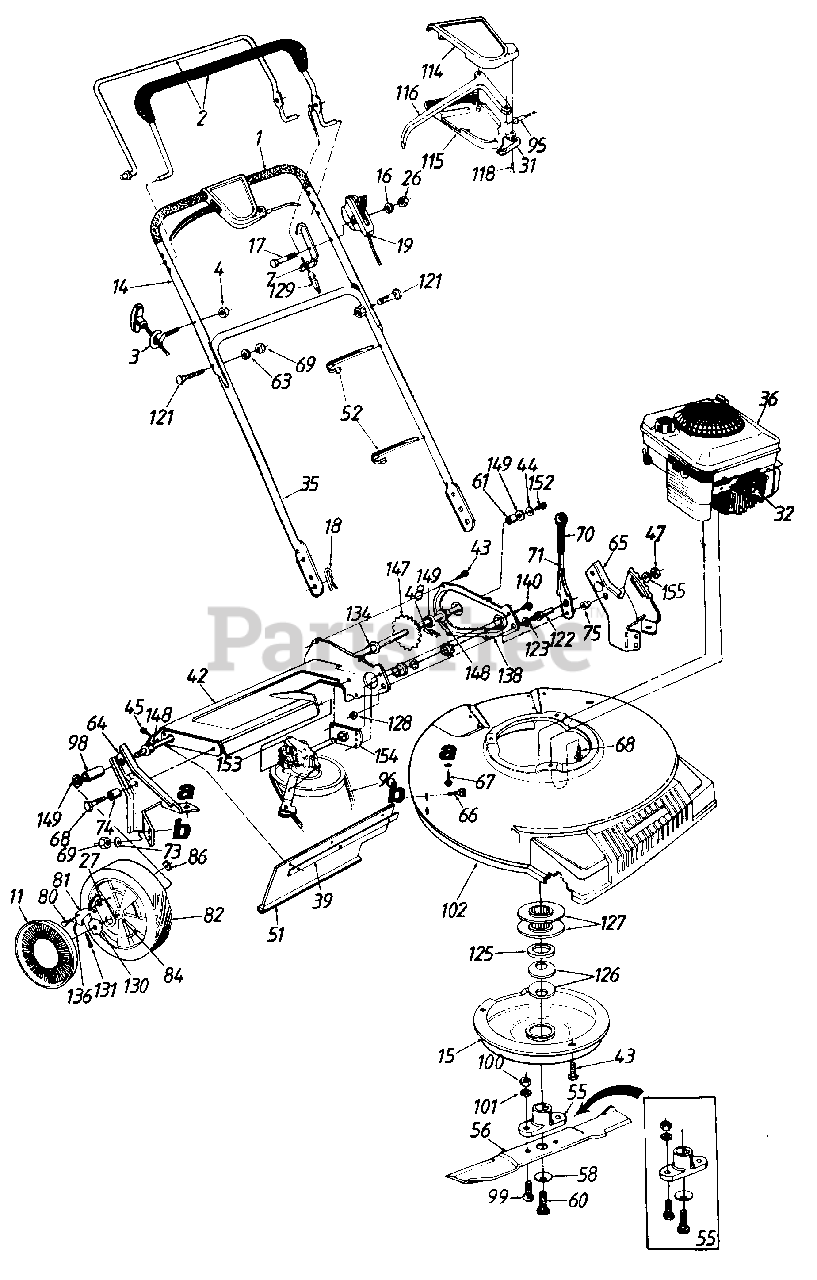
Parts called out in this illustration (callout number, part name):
1	Grip
2	Control Handle Ass'y.
3	Rope Guide Bolt
4	Hex L-Nut 1/4-20 Thd.
7	Cable Brkt.
11	Hub Cap
14	Upper Handle
17	Hex Bolt 1/4-20 x 1.875" Lg.
18	Internal Cotter Pin 5/16" Dia.
19	Throttle Control Ass'y.
26	Hex Nut 1/4-20 Thd.
27	Pawl Plate
31	S.P. Control Cover
32	Spark Plug Insulator
35	Lower Handle
36	Engine
39	Retaining Strip
42	Chain-Axle Ass'y.
43	Hex B-Tap Scr. 1/4" x .38"
44	Bell-Wash. 1/4" I.D.
45	Hex AB-Tap Scr. 1/4 x .62"
47	Hex Patch L-Nut 3/8-24 Thd.
48	#48 Chain .500" Pitch x 38 Links
51	Rear Flap 3.75" x 17.30" Lg.
52	Cable Tie
55	Blade Adapter Kit
56	21" Mulching Blade
58	Bell-Wash. .47" I.D. x 1.14" O.D.
60	Hex Bolt 7/16-20 x 2.5"
61	Spacer. 513" I.D.
63	L-Wash. 5/16" I.D.
64	R.H. Handle Wheel Brkt. Ass'y.
65	L.H. Handle Wheel Brkt. Ass'y.
66	Carriage Bolt 5/16-18 x .62"
67	Hex B-Tap Scr. 5/16-18
68	Hex TT-Tap Scr. 3/8-16
69	Hex Nut 5/16-18 Thd.
71	Height Adj. Lever
73	Bell-Wash. 5/16" I.D.
74	Spacer.383" I.D.
75	Shld. Spacer .5" Dia.
80	Shld. Scr. .342" Dia. x .268
81	Pawl
82	Wheel Ass'y. Comp.-Rear
84	Sleeve Bearing 1/2" I.D.
86	Flat Nut 1/4-20 Thd.
95	S.P. Cable-44" Lg.
96	"V"-Belt
98	Sleeve.526" I.D.
99	Hex Bolt 3/8-24 x 1.0" Lg.
100	Hex Nut 3/8-24 Thd.
101	L-Wash. 3/8" I.D.
115	Self-Propelled Control Cover
116	Control Lever
118	Fl-"C"-Sunk Hd. Tap Scr. #10 x 75n Lg.
121	Curved Carr. Bolt 5/16-18 x 1.38" Lg.
122	Shld. Pin 1.43" Lg.
123	L-Wash. 818n I.D.
125	Crankshaft Spacer
126	Bell-Wash. 1.01" I.D.
127	Serrated Pulley Half
128	Hex Jam Nut 3/8-24 Thd.
129	Control Cable-36"
130	Ratchet Wheel 1.62" O.D.
131	Cotter Pin 1/8" Dia. x 1
134	Hex Flange Bearing
136	Spring-Nylon
147	Rear Shaft Ass'y. 21.44" Lg.
148	Hex Flange Brg. .506" I.D.
149	Fl-Wash. .531" I.D. x .930"
152	Hex Bolt 1/4-20 x .62" Lg. (Grade 5)
153	Transmission Comp.
155	Fl-Wash. 885" I.D.
